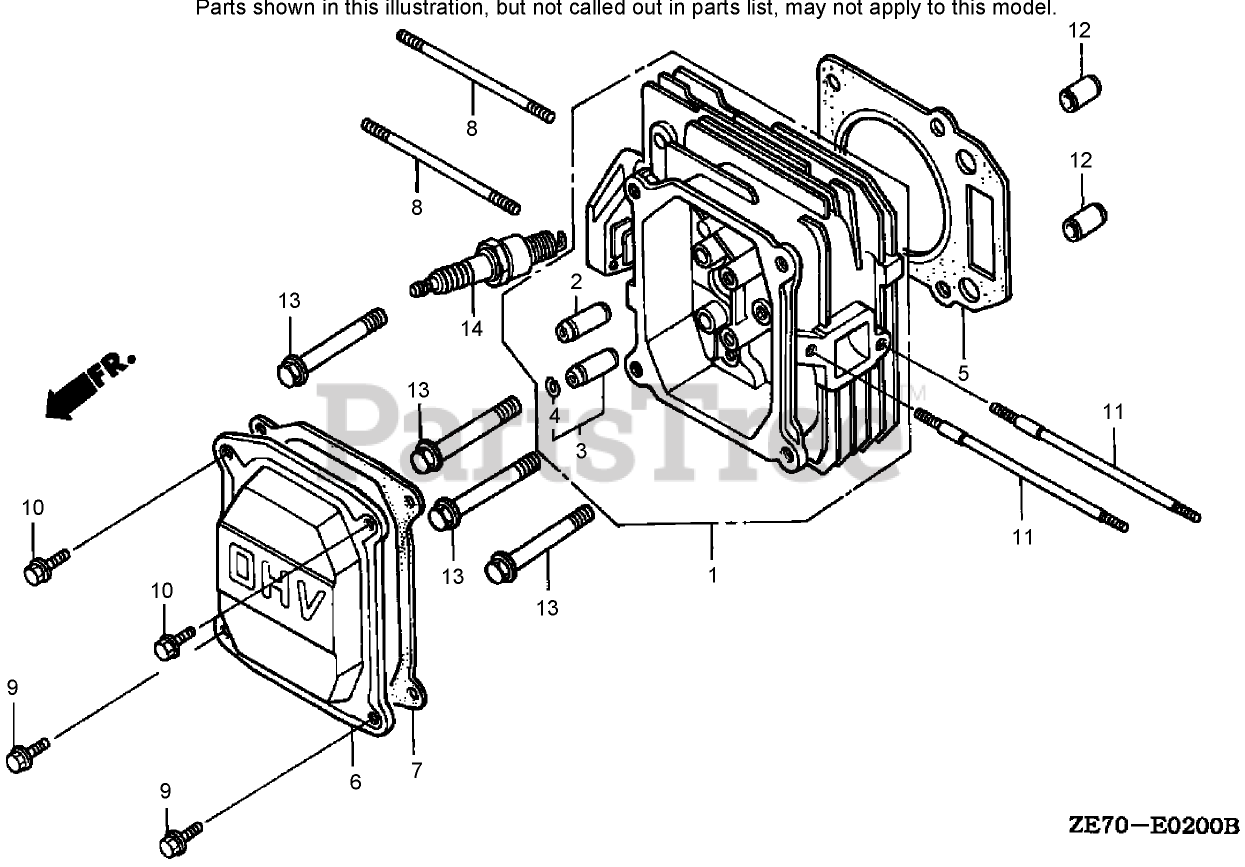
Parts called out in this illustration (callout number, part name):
1	HEAD-CYLINDER
2	GUIDE-VALVE (O S)
3	GUIDE-VALVE, EXHAUST (O S)
4	CLIP-GUIDE, VALVE
5	GASKET-HEAD, CYLINDER
6	Cover-Head
7	Gasket-COVER, Cylinder Head
8	BOLT-STUD (6X85)
9	BOLT-FLANGE (6X12) (C T200)
10	BOLT-FLANGE (6X12) (C T200)
11	BOLT-STUD (6X109)
12	PIN-DOWEL (10X16)
13	BOLT-FLANGE (8X50)
14	SPARK PLUG (B P R4E S) (N G K)
14	SPARK PLUG (W14E P R-U) (DENSO)
14	SPARK PLUG (B P R 5E S) (N G K)
14	SPARK PLUG (W16E P R-U) (DENSO)
14	SPARK PLUG (B P R 6E S) (N G K)
14	SPARK PLUG (W20E P R-U) (DENSO)
